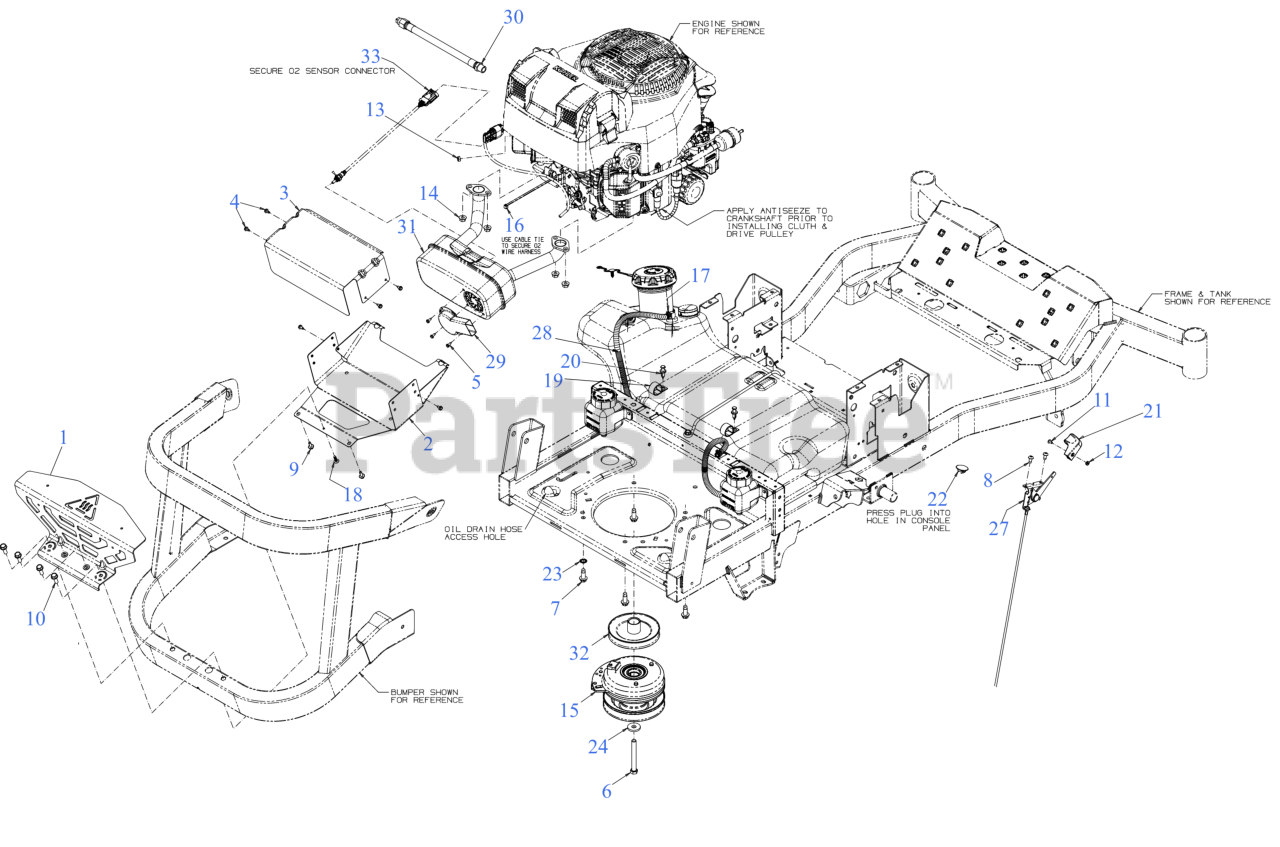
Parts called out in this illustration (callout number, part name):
1	MUFFLER COVER (REAR) (BLACK)
1	NUT RIVET 5/16-18
2	MUFFLER SHIELD (LOWER)
3	MUFFLER SHIELD (TOP)
4	HEX SCREW AB-TAP #10 x .50
5	HEX SCREW WASHER HD #8-18 x 0.500
6	SCREW 7/16-20 x 3.5 GR5
7	SCREW 3/8-16 x 1
8	SCREW 1/4-20 x .5
9	SCREW M6-1 x .625
10	SCREW 5/16-18 x .875 GR5
11	SCREW #8-32X.38 LG
12	HEX NUT 8-32
13	HEX NUT 1/4-20
14	HEX FLANGE NUT M8X
15	ELECTRIC PTO CLUTCH
16	7" CABLE TIE
17	HOSE CLAMP 1/20
18	RATCHET CLIP (.188 x .85)
19	CLAMP 1.00 DIA x .625
20	PLASTIC RIVET
21	THROTTLE CONTROL KNOB
22	CHOKE PLUG
23	LOCK WASHER 3/8
24	FLAT WASHER .445 x 1.248 x .170
27	THROTTLE CABLE (51.0 LG)
28	FUEL HOSE LOW PERMEATION 45"
29	EXHAUST DELECTOR (LONG)
30	OIL DRAIN HOSE (11.26" 3/8 NPT)
31	EXHAUST MUFFLER
32	TRANSMISSION DRIVE PULLEY
33	O2 SENSOR CLIP
